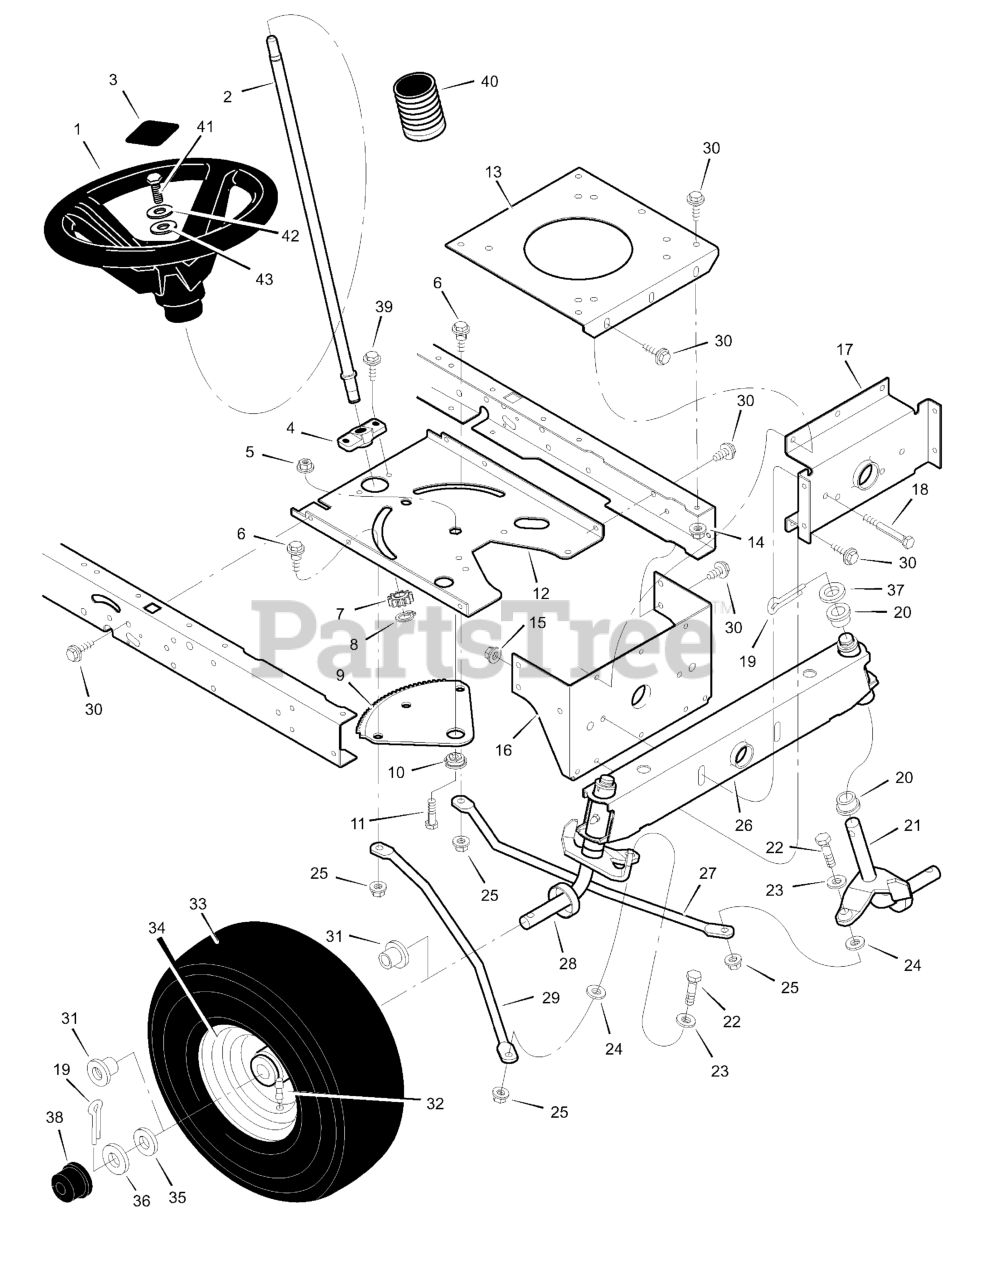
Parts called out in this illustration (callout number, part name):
1	Wheel, Steering
2	Post, Steering
3	Insert, Steering Wheel
4	Bearing
5	Nut, Flange
6	Bolt, Shoulder
7	Gear, Pinion
8	Ring, Snap
9	Gear, Sector
10	Bearing
11	CAPSCREW, Hex Head, 5/16-18 x 1
12	Plate, Steering
13	Plate, Engine
14	Nut, Flange
15	Nut, Flange
16	Bracket, Hanger
17	Axle, Hanger
19	Pin, Cotter
20	Bearing
21	Spindle Assembly, Left
22	Bolt
23	Washer
25	Nut, Flange
26	Axle Assembly
27	Drag Link, Left
28	Spindle Assembly, Right
29	Drag Link, Right
31	Bearing, Wheel
32	Stem, Valve
33	Tire *
34	Wheel and Tire Assembly
38	Hub Cap
40	Bellows
42	Lockwasher
